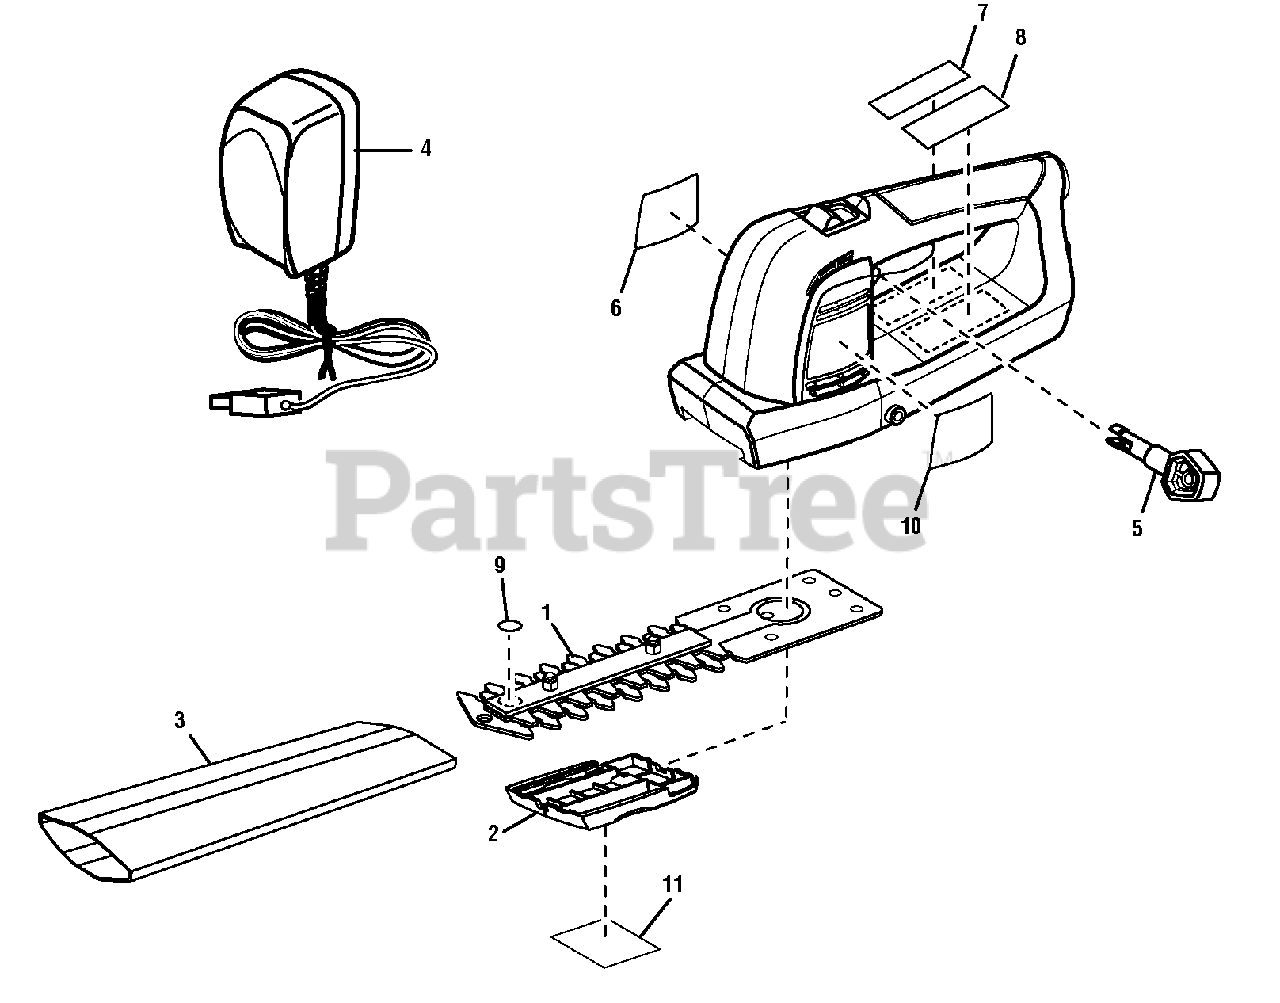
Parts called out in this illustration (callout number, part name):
1	Shrubber Blade Assembly
2	Bottom Cover
5	Lock-out Pin
7	No Hands Warning Label
9	No Hands Label
11	Padlock/Lock Pin Warning Label
